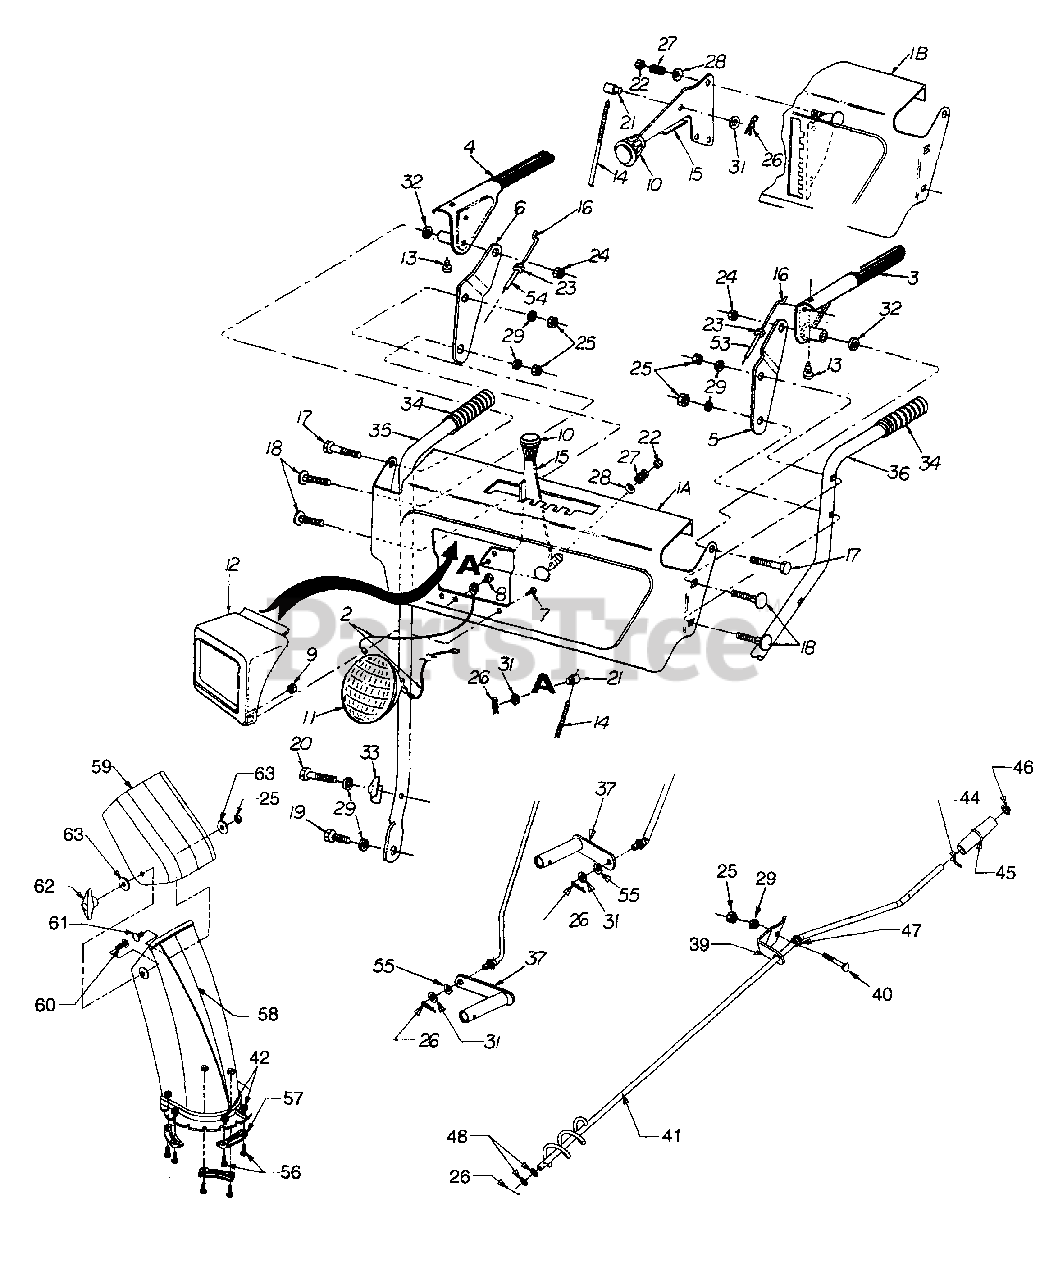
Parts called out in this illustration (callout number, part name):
3	Clutch Lever LH
4	Clutch Lever RH
8	Hex B-Tap Scr. 1/4-28 x .25" Lg.
9	Self Threading Nut .25
10	Ball Knob
11	Sealed Beam 18 Watt
12	Headlight Bezel
13	Rubber Bumper
14	Shift Rod
15	Shift Handle
16	"Z" Fitting
17	Hex Scr. 5/16-18 x 2.00
18	Carriage Bolt 5/16-18 x 1.50
19	Hex Bolt 5/16-18 x .75" Lg.
20	Hex Screw 5/16-18 x 1.75" Lg.
21	Adjustment Ferrule
22	Hex Nut 3/8-24
23	Hex Nut 10-24
24	Hex L-Nut 5/16-18
25	Hex Nut 5/16-18
26	Int. Cotter Pin 5/16 Dia.
27	Compression Spring .38 ID x .88 Lg.
28	Bell-Wash. .400 ID x .88 OD x .06
29	L-Wash. 5/16 ID
31	Flat Washer .34 ID x .63 OD
32	Spacer
33	Handle Tab
41	Chute Crank Ass'y.
42	Hex Flange Nut 1/4-20
44	Roll Pin .125 Dia. x .62
45	Knob-Chute Crank
46	Cap Speed Nut 3/8" Rod
47	Plastic Bushing
48	Flat Washer .385 ID x .62 OD x .06
53	Auger Clutch Cable (w/"Z" Fitting)
54	Drive Clutch Cable (w/"Z" Fitting)
55	Spring Wash. .317" I.D. x .625" O.D.
56	Hex Bolt 1/4-20 x .75" Lg. (Gr. 5)
57	Chute Keeper
58	Lower Chute
59	Upper Chute
60	Carriage Bolt 5/16-18 x 1" Lg.
61	Carriage Bolt 5/16-18 x .75" Lg.
63	Fl-Wash. .34" I.D. x 1.125" O.D.
